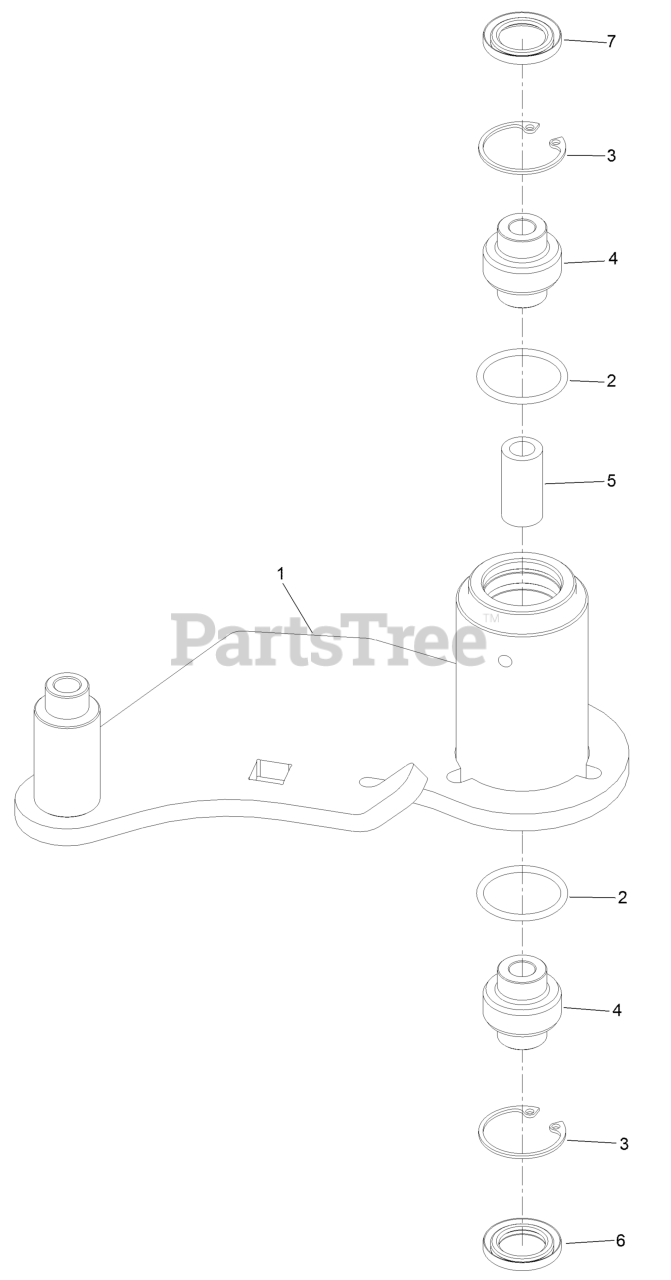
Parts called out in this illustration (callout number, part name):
1	Idler-Deck
3	RING-SNAP
4	BEARING-SPHERICAL
6	SEAL-LIP, DOUBLE
7	SEAL-LIP, SINGLE
